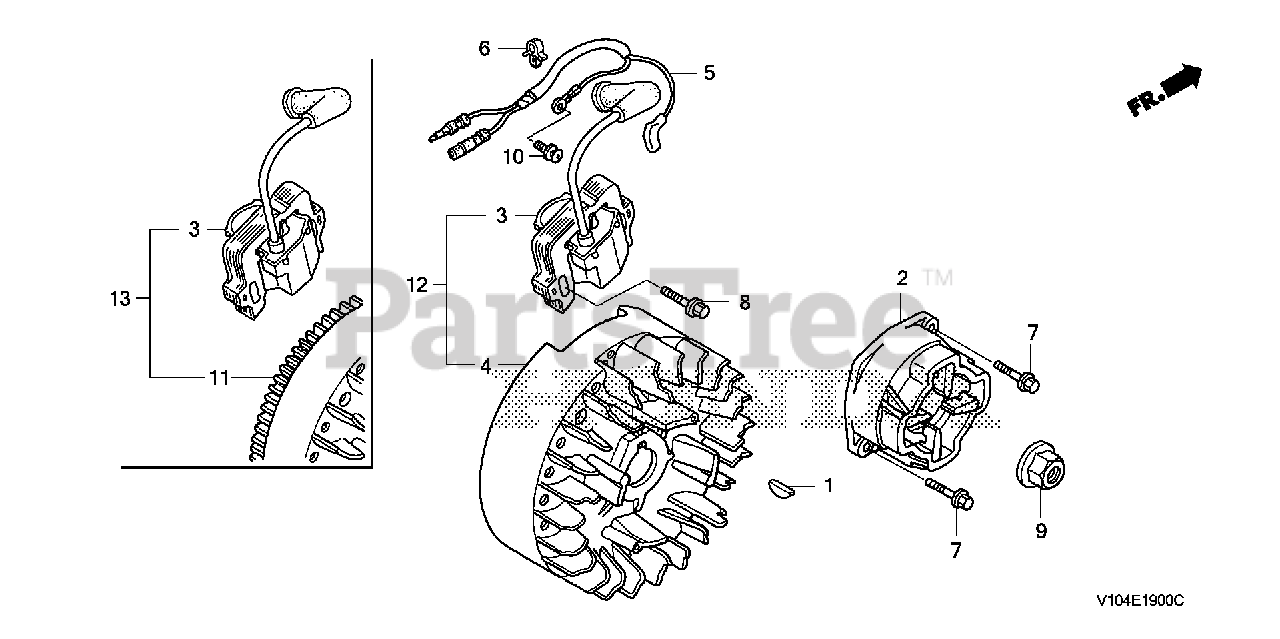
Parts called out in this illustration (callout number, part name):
1	KEY, SPECIAL WOODRUFF (25X18)
3	COIL ASSY., IGNITION (USE FOR F/W OF TEC) (TEC)
4	FLYWHEEL COMP. (TEC) (USE FOR IGN. COIL OF TEC) (USE FOR TEC IGNITION COIL)
5	WIRE, STOP SWITCH
6	CLIP, BRAKE PIPE (A)
8	BOLT, FLANGE (6X20) (CT200)
9	NUT, SPECIAL (14MM)
10	SCREW-WASHER (5X8)
